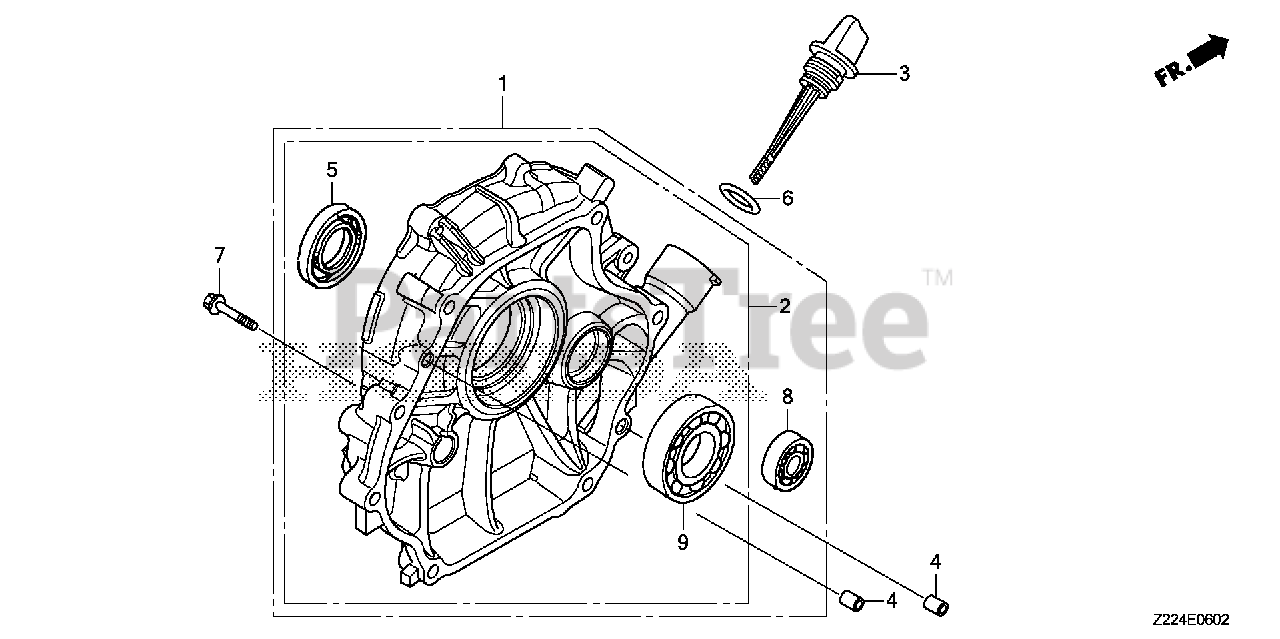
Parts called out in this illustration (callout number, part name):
1	COVER ASSY., CRANKCASE (E-TYPE)
3	CAP, OIL FILLER
4	PIN, DOWEL (8X12)
5	OIL SEAL (35X52X8) (NOK)
6	O-RING (26X2.7)
7	BOLT, FLANGE (8X40)
8	BEARING, RADIAL BALL (6202)
9	BEARING, RADIAL BALL (6207)
